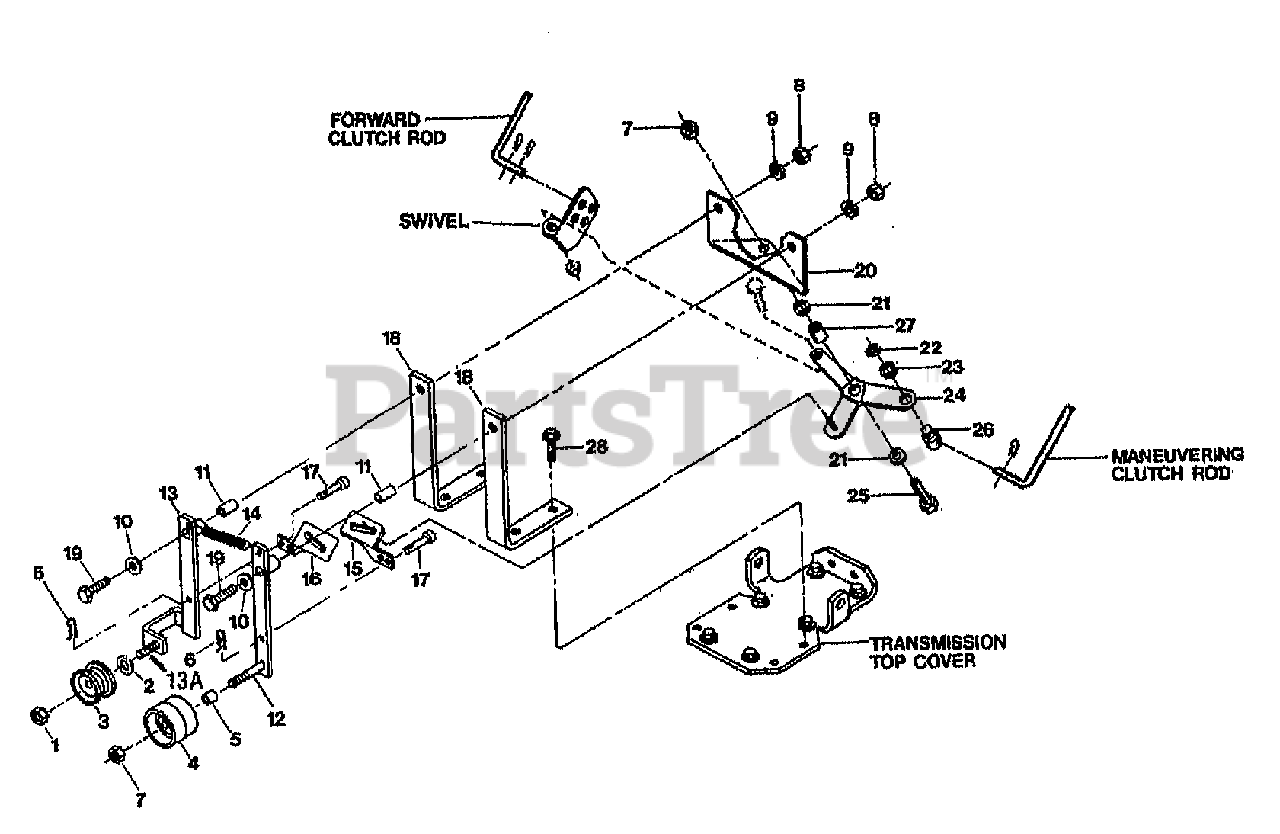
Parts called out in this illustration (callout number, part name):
1	NUT-LOCK 3/8-16 NYLON ZP
2	BUSHING-.54X.38X.08
3	IDLER-REV
3	PULLEY-IDLER REVERSE
4	PULLEY-IDLER FORWARD
5	SPACER-IDLER FWD
6	PIN-CLIP .08
7	NUT-H/LK 3/8-16
8	NUT-HEX 5/16-18 ZP
9	WASHER-LK .312 ZP
10	WASHER-#.75X.32X.09 ZP
11	BUSHING-.438X.323X.712
12	ARM-IDLER FWD PNT
13	IDLER-REV
13	ARM-IDLER REV RED
13A	SCR-HH 3/8-16X1.25
14	SPRING-.436 X 3.25
15	LINK-FWD
17	PIN-CLEVIS .375X.719 ZP
18	MOUNT BAR-PNT (20691)
19	SCR-HH 5/16-18X2.25 G5ZP
20	SHIFT BASE-OPC PNT
21	SPACER-.88X.385X.09 ZP
22	RING-KLIP .500 ZINC
23	WASHER-#.88X.51X.063 ZP
24	BELLCRANK-OPC PNT
25	SCR-HH 3/8-16X1.25
26	PIVOT-ROD (FOR MANEUVERING CLUTCH LEVER)
27	BUSHING-.5X.38X.4
28	SCR-HFLK 5/16-18X1.00 ZP
